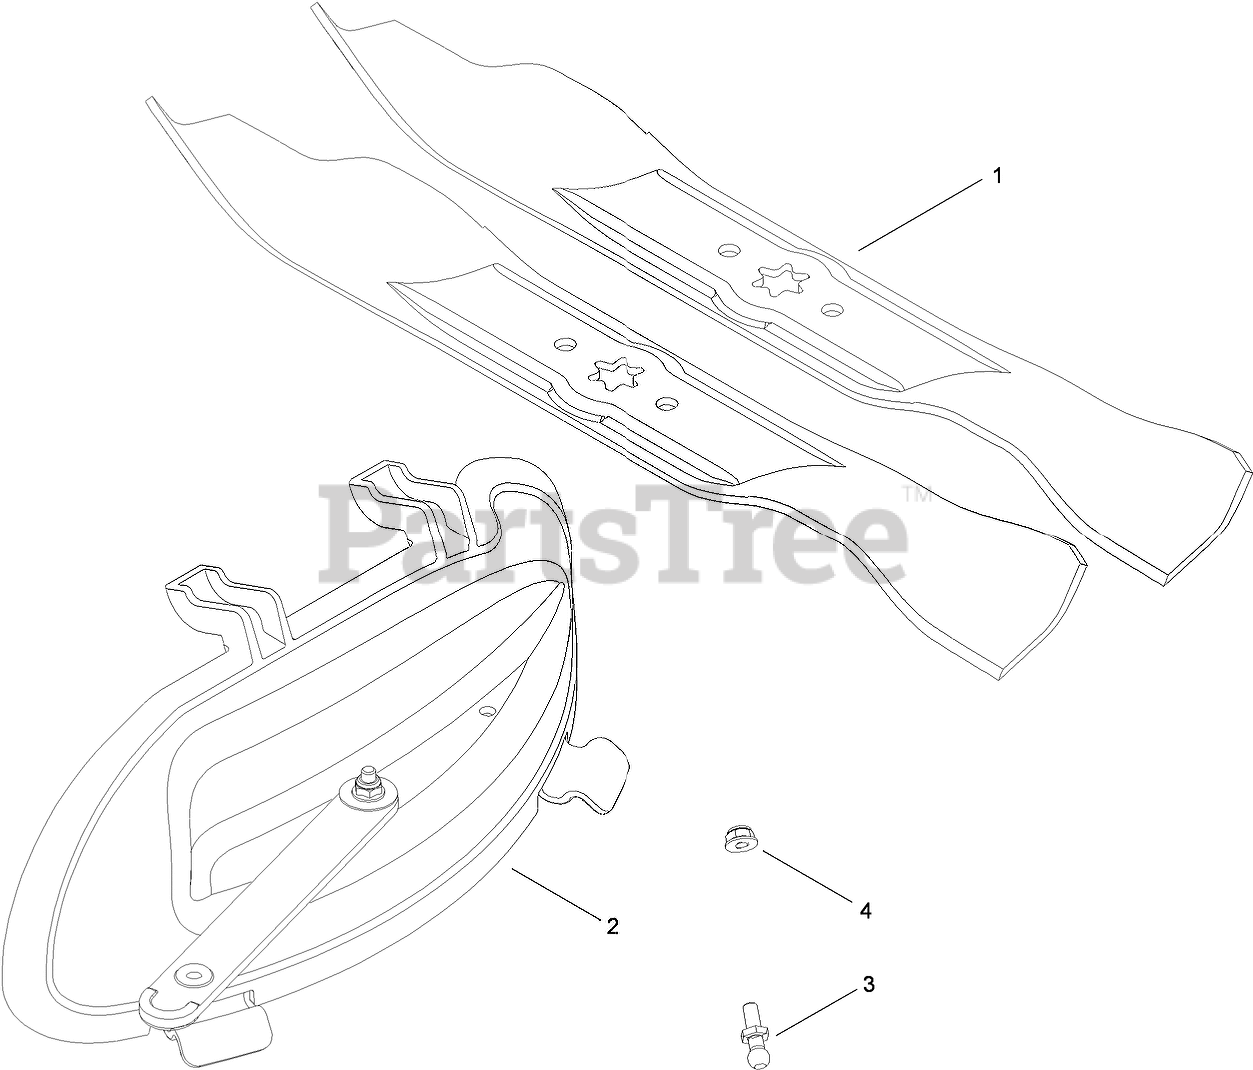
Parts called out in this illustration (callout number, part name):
2	PLUG-MULCH
3	PIN-CATCHER, GRASS
4	NUT-LOCK, FLANGE
